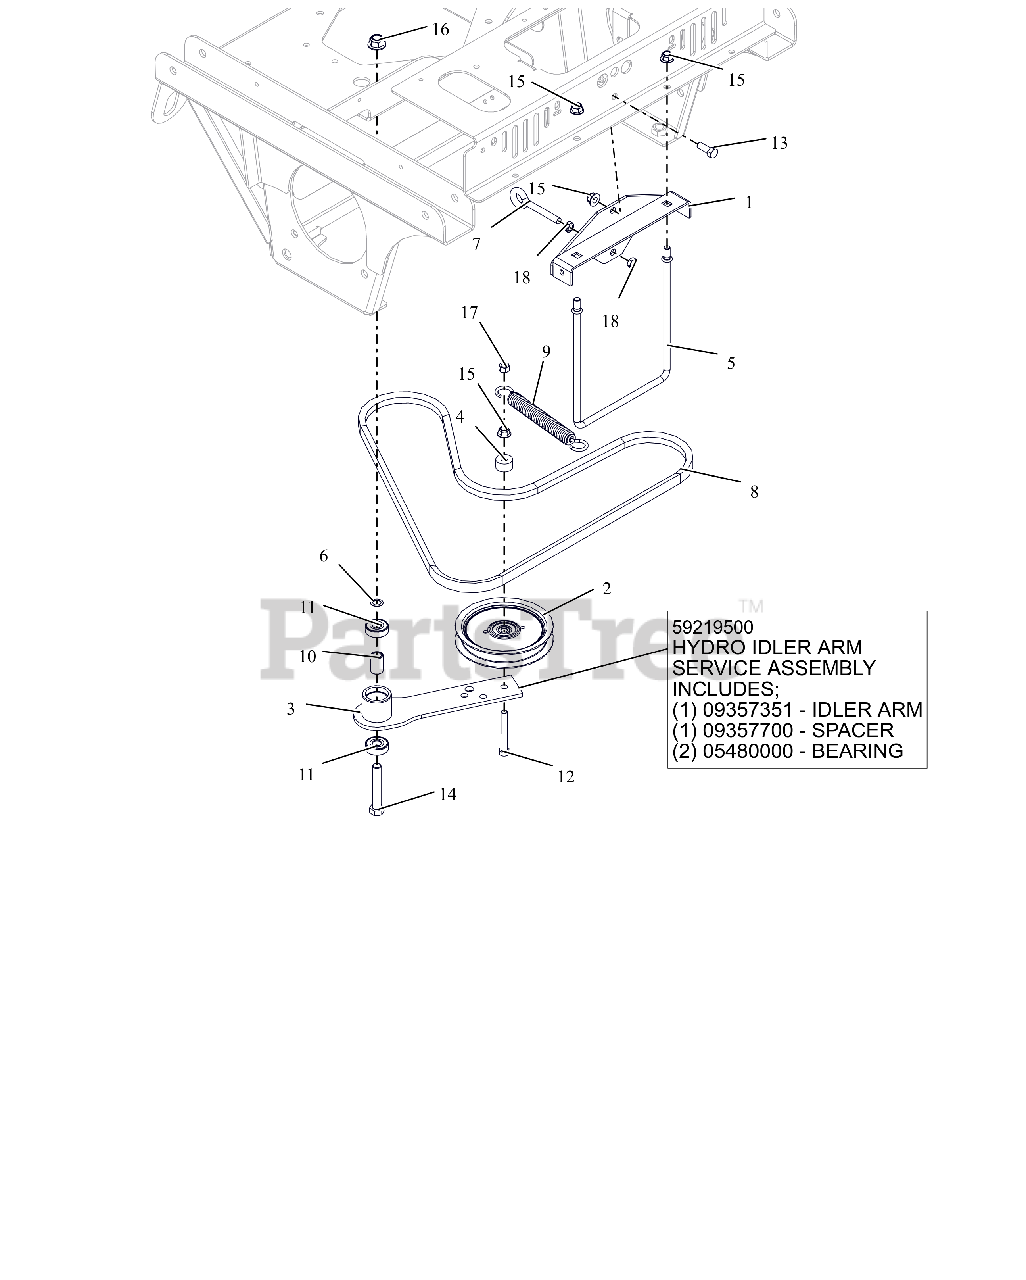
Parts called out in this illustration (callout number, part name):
1	SPRING ANCHOR BRKT WMT - BLACK
2	IDLER, FLAT-5.00X.75
3	HYDRO DRIVE IDLER ARM WMT- BLK
3	KIT, HYDRO IDLER ARM PT200/400
4	SPACER .390X1.000X.562
5	ROD, BRAKE MTG
6	WASHER, .500X.750X.020 THRUST
7	BLT-EYE .375-16X2.50 YWZC
8	V-BELT, COGGED B-RAW EDGE
9	SPRING, EXTENSION
10	SPACER .510 X .75 X 1.1485
11	BRG-BALL .500X1.38X.437
12	BLT, HEX .38-16X2.75 G5 ZCC
13	BLT,HEX .38-16X1.00 G5 ZCC
14	BLT, HEX .50-13X3.00 G5 ZCC
15	NUT,NYL-FLG .38-16 GF ZCC
16	NUT,NYL-FLG .50-13 GF ZCC
17	NUT-LK-CTR .38-16 ZC120
18	NUT-JAM .375-16 G2 ZCC
